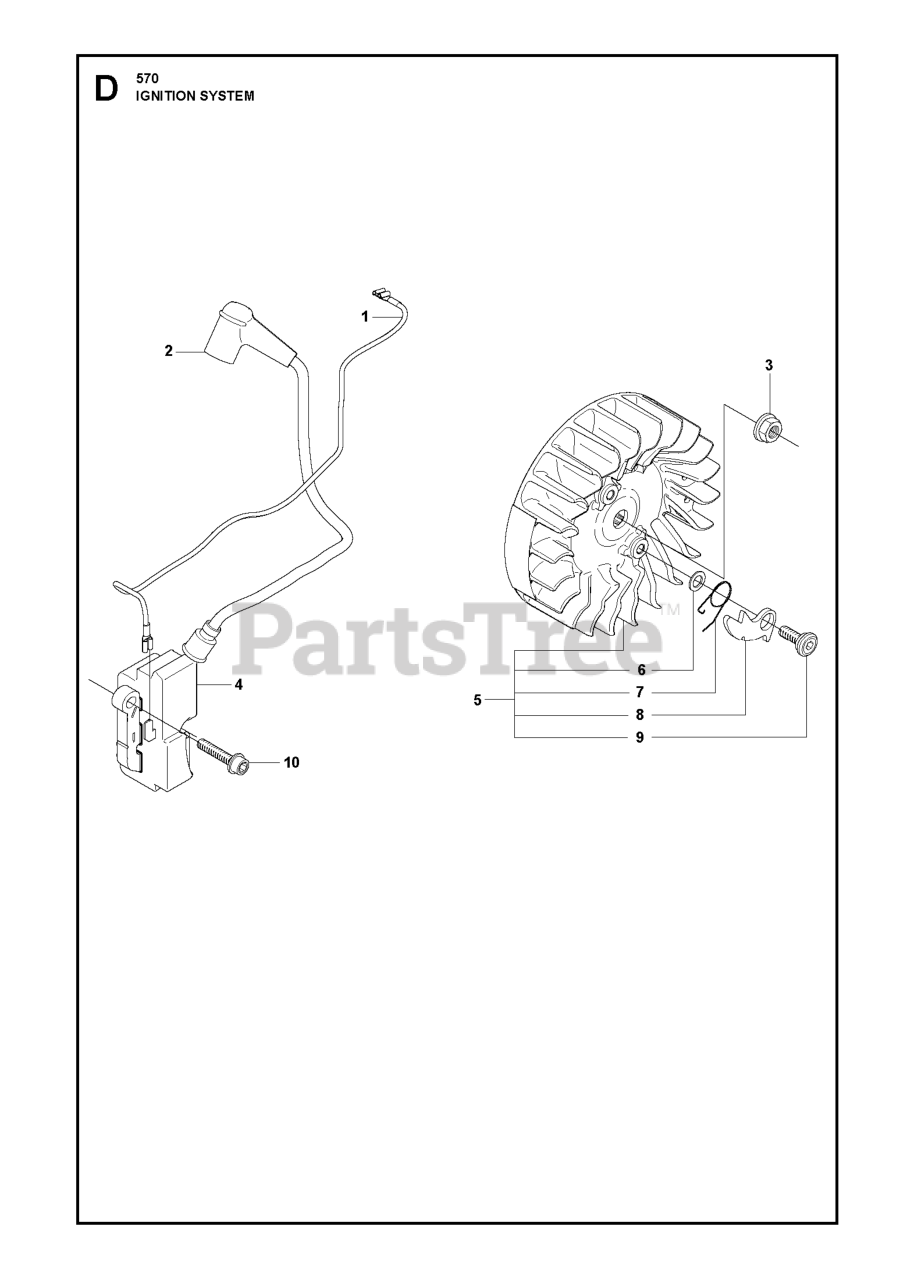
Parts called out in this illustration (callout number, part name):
1	SHORTING LEAD
2	SPARK PLUG CONN. KIT
3	NUT W/ WASHER
4	IGNITION MODULE
9	SCREW M5X14
